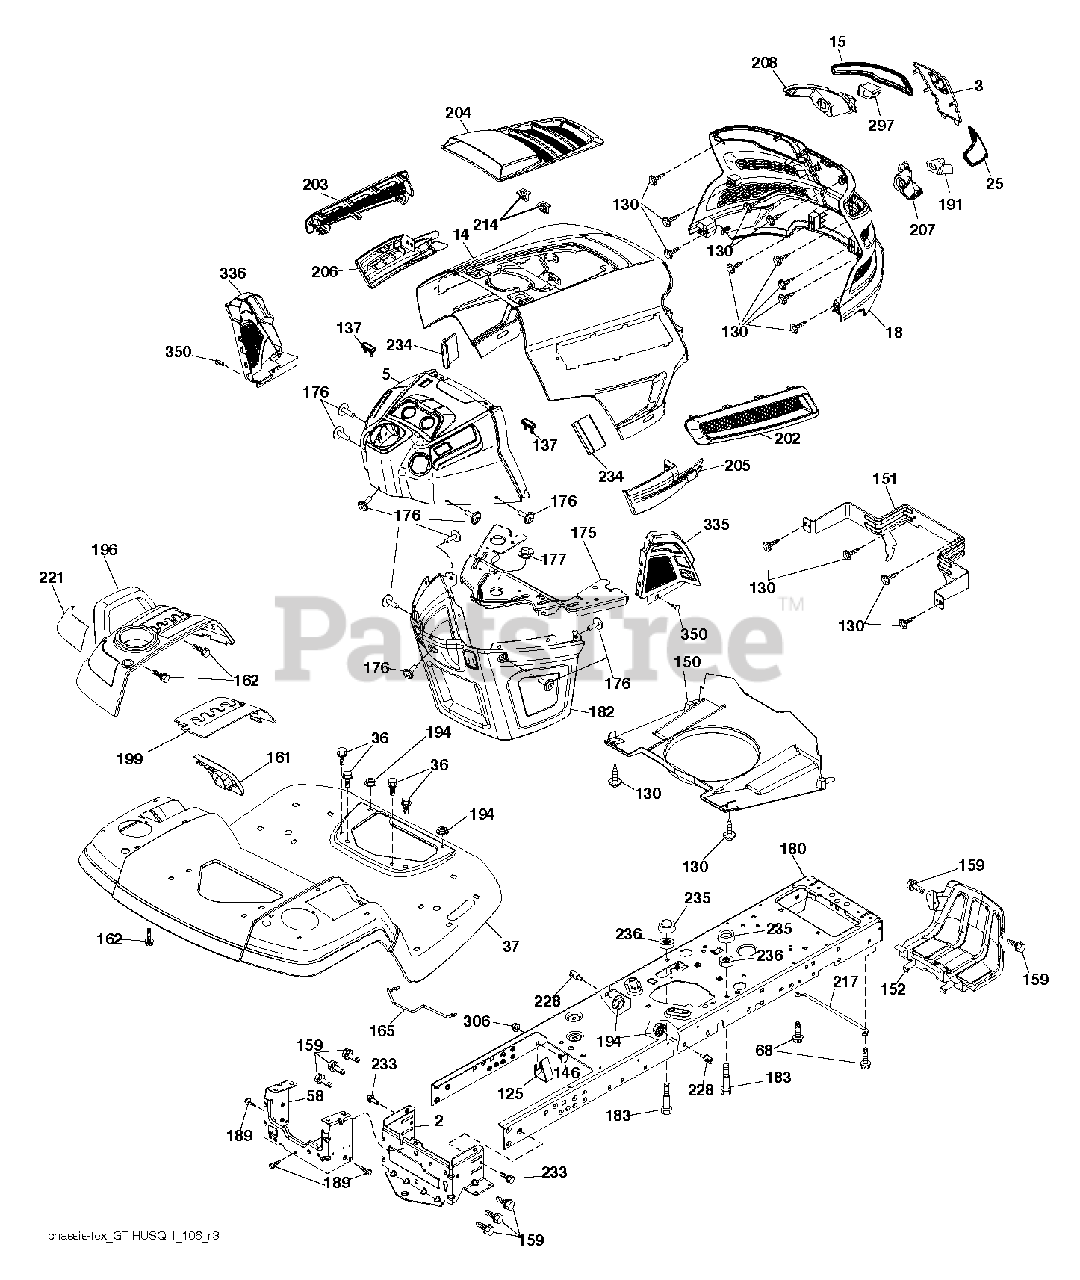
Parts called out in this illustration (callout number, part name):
2	DRAWBAR.LOWER.2PC.18/22
3	APPLIQUE.SUBASM.GT.HUSQ.II
5	DASH.UPP.GT2.DR.PTO.DCKLFT.MC
14	HOOD.ASM.HUSQVARNA.GT.TEX.ORAN
15	LENS.HEADLIGHT.LH.GTII.2011
18	GRILLE.SUBSTRATE.2011.
25	LENS.HEADLIGHT.RH.GTII.2011
36	SCREW 5/16"
37	FENDER.PNT.TX.GT.CH/FW/DL.HUSQ
58	DRAWBAR.UPPER.2PC,LRG.FENDER
68	SCREW LT
125	CLIP.FUEL.LINE
130	SCREW.#10 X 0.750.BOS
137	BUMPER DASH
146	BOLT.RDHD.SHT.SQNK.3/8-16X5/8
150	AIR.DUCT.GTV.BLACK
151	BRACKET.PIVOT.HOOD.GT.HUSQ.II
152	SHIELD.BROWNING.PNT.GT.V2
159	SCREW, 3/8-16X3/4
161	CONSOLE.WINDOW.FUEL.HUSQ.GT
162	SCREW.HI-LO.CONSOLE
165	SUPPORT.TANK.REAR.B/TE
175	PLATE.CROSSMEMBER.HUSQ
176	SCREW.#10-24X5/8.RN.QU
177	BUSHING, STEERING
180	CHASSIS.TEX.BOLTED
182	DASH.LOWER.COMMON.12V.ADAPTOR
183	BOLT.5/16-18X1-1/4 FULL THD
189	SCREW
191	INSERT.REFLECTIVE.RH.HUSQ.GTII
194	NUT LOCK HEX FLANGE 5/16-18
196	CONSOLE.ASM.DECKLIFT.HUSQGT.DL
199	PLATE.DECK.LIFT.HUSQVARNA.GT
202	VENT.SIDE.RH.GT.HUSQ.II.
203	VENT.SIDE.LH.GT.HUSQ.II.498
204	VENT.TOP.HUSQ.GT2
205	SIDE.TRIM.RH.GT.HUSQ.II
206	SIDE.TRIM.LH.GT.HUSQ.II.GRAY
207	BEZEL LIGHT.RH.GT.II.MYLAR
208	BEZEL LIGHT.LH.GT.II.MYLAR
214	CLIP.RETAINER.TINNER.
217	ROD.PIVOT.HOOD
221	REFLECTOR.LH.TEX GT HU
228	STUD.FASTNER.W/ANTI-ROTATE
233	BOLT.SHOULDER
234	BUMPER.HOOD.TEX.HUSQVARNA
235	SPACER FENDER
236	NUT.CENTERLOCK.5/16-
297	INSERT.REFLECTIVE.LH.HUSQ.GTII
306	NUT LOCK FLG 3/8-16 UNC
335	COVER.LOWER.DASH.RH.BLACK
336	COVER-LH.LOWER.DASH.GT2.BLACK
350	CLIP.X-MAS.TREE
